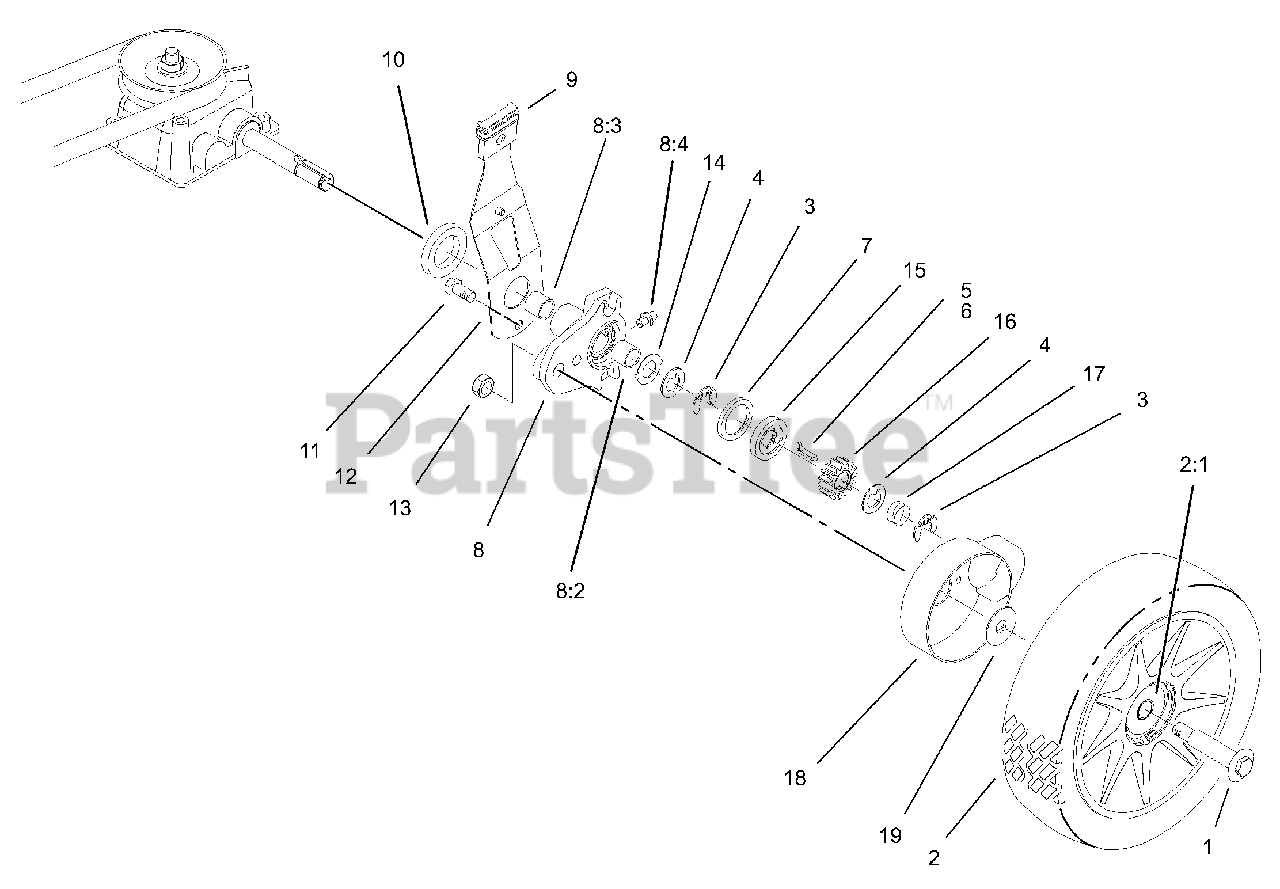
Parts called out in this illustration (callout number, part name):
1	BOLT-SHOULDER
2	WHEEL AND TIRE ASM
3	KLIPRING-LOCKING
4	WASHER-THRUST, KEYED
5	KEY-ROCKING, LH
6	KEY-ROCKING, RH
7	RING-FRICTION
8	REAR HEIGHT ADJUSTMENT ARM ASM
8:4	FITTING-GREASE
9	KNOB-LEVER, HEIGHT ADJUSTMENT
10	SPACER-AXLE SHAFT
11	SCREW-HWH
12	REAR SPRING ARM ASM
14	WASHER-ARM, PIVOT
15	WASHER-CLUTCH
16	GEAR-PINION
17	SPRING-COMPRESSION
18	COVER-WHEEL
19	WASHER-STEPPED
